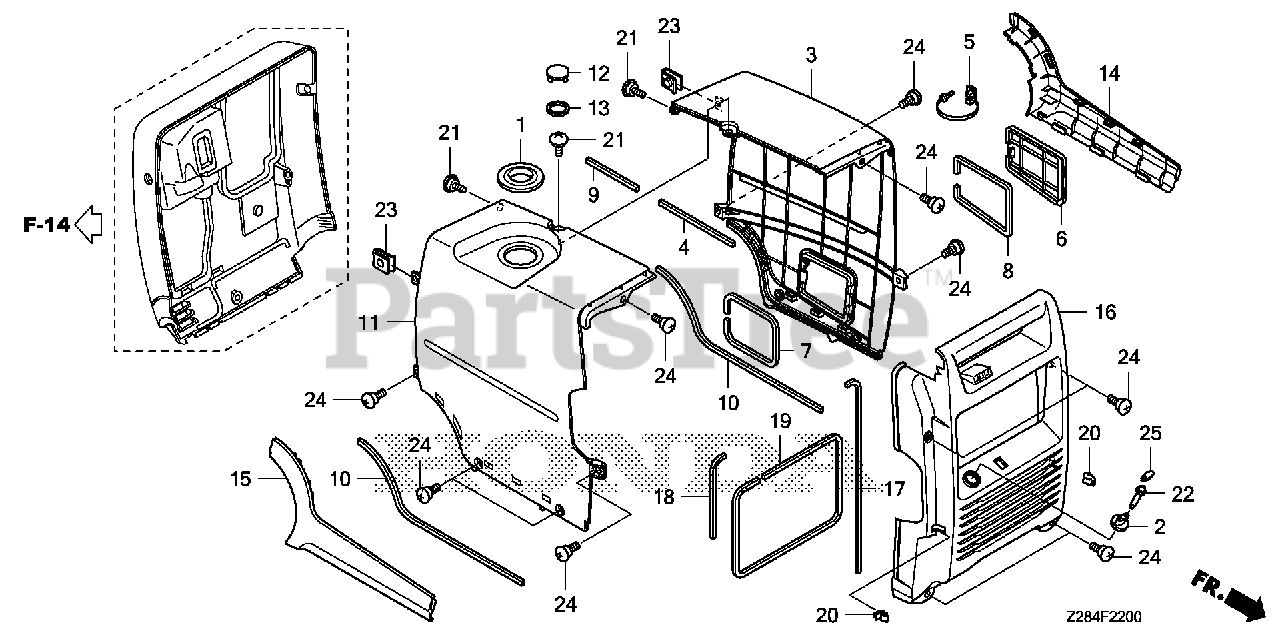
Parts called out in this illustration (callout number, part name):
1	SEAL, FUEL FILLER NECK
2	KNOB, ENGINE SWITCH
3	COVER, R. SIDE *R280* (POWER RED)
4	SEAL A, SIDE COVER (UPPER)
5	KNOB, OIL MAINTENANCE COVER
6	COVER, OIL MAINTENANCE *R280* (POWER RED)
7	SEAL, R. SIDE COVER
8	OIL SEAL, MAINTENANCE COVER
9	SEAL B, SIDE COVER (UPPER)
10	SEAL, SIDE COVER (LOWER)
11	COVER, L. SIDE *R280* (POWER RED)
12	CAP, SIDE COVER *R280* (POWER RED)
13	SEAL, SIDE COVER CAP
14	PLATE, R. SIDE (LOWER) *NH314* (CONDUCT GRAY)
15	PLATE, L. SIDE (LOWER) *NH314* (CONDUCT GRAY)
16	COVER, FR. *NH314* (CONDUCT GRAY)
17	SEAL A, FR. COVER
18	SEAL B, FR. COVER
19	SEAL C, FR. COVER
20	STOPPER, HANDLE
21	SCREW, SPECIAL (6MM)
22	SCREW, KNOB (5X27.5)
23	NUT, SPRING (6MM)
24	SCREW, SPECIAL (6X15)
